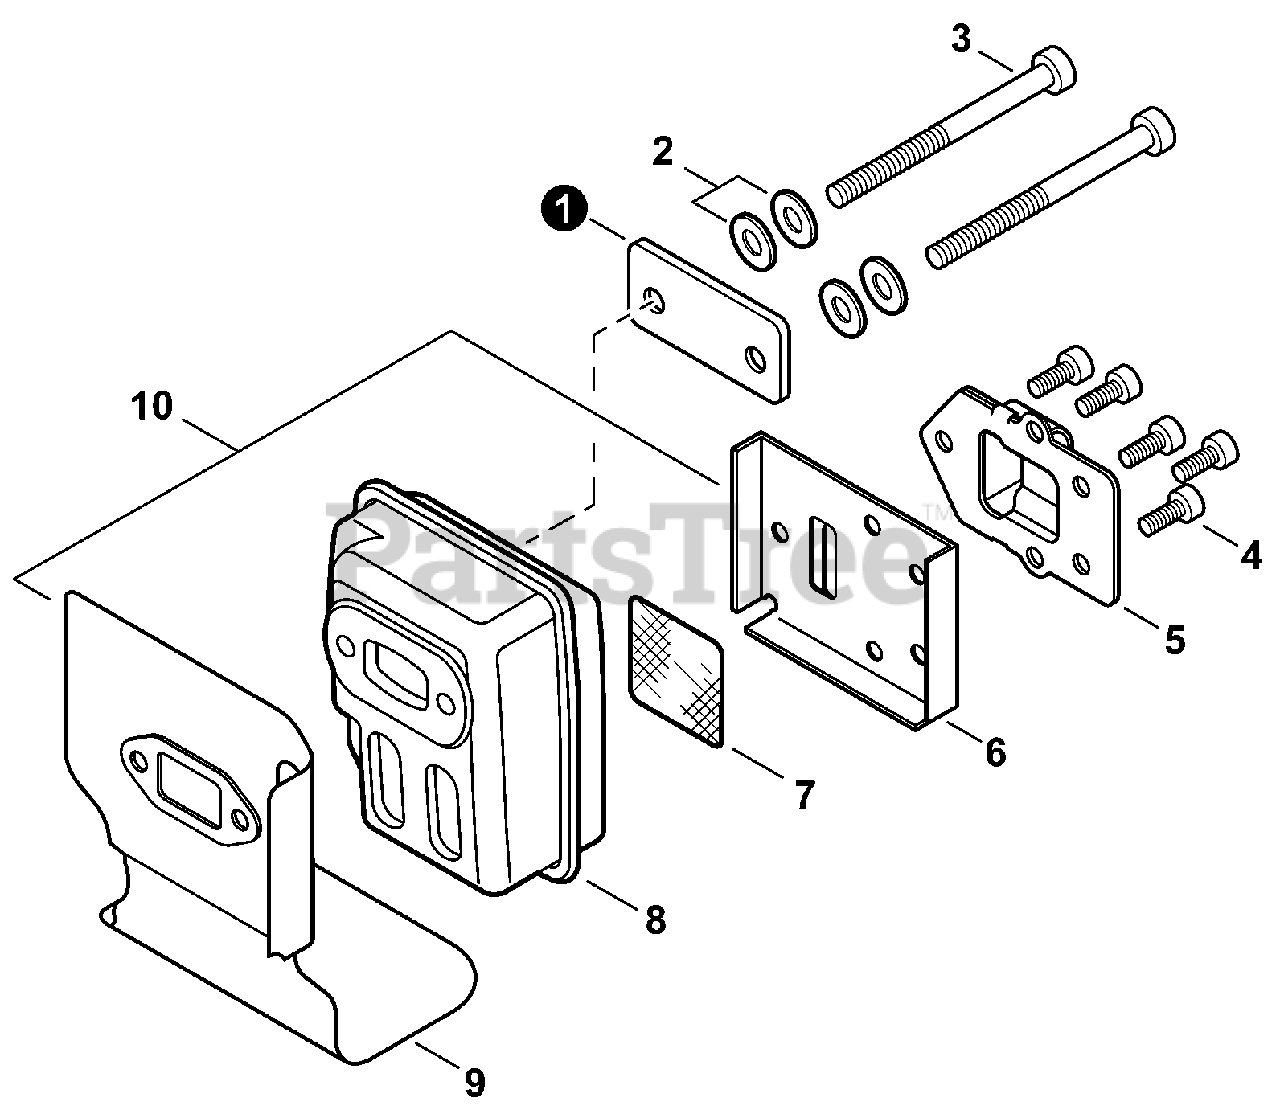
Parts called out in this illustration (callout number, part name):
1	PLATE, EYE
2	CONICAL WASHER
3	BOLT 5×55
4	SCREW 4×10
5	GUIDE, EXHAUST
6	GASKET, EXHAUST
7	SCREEN, SPARK ARRESTER
8	MUFFLER
9	HEAT SHIELD, EXHAUST
10	GASKET KIT
